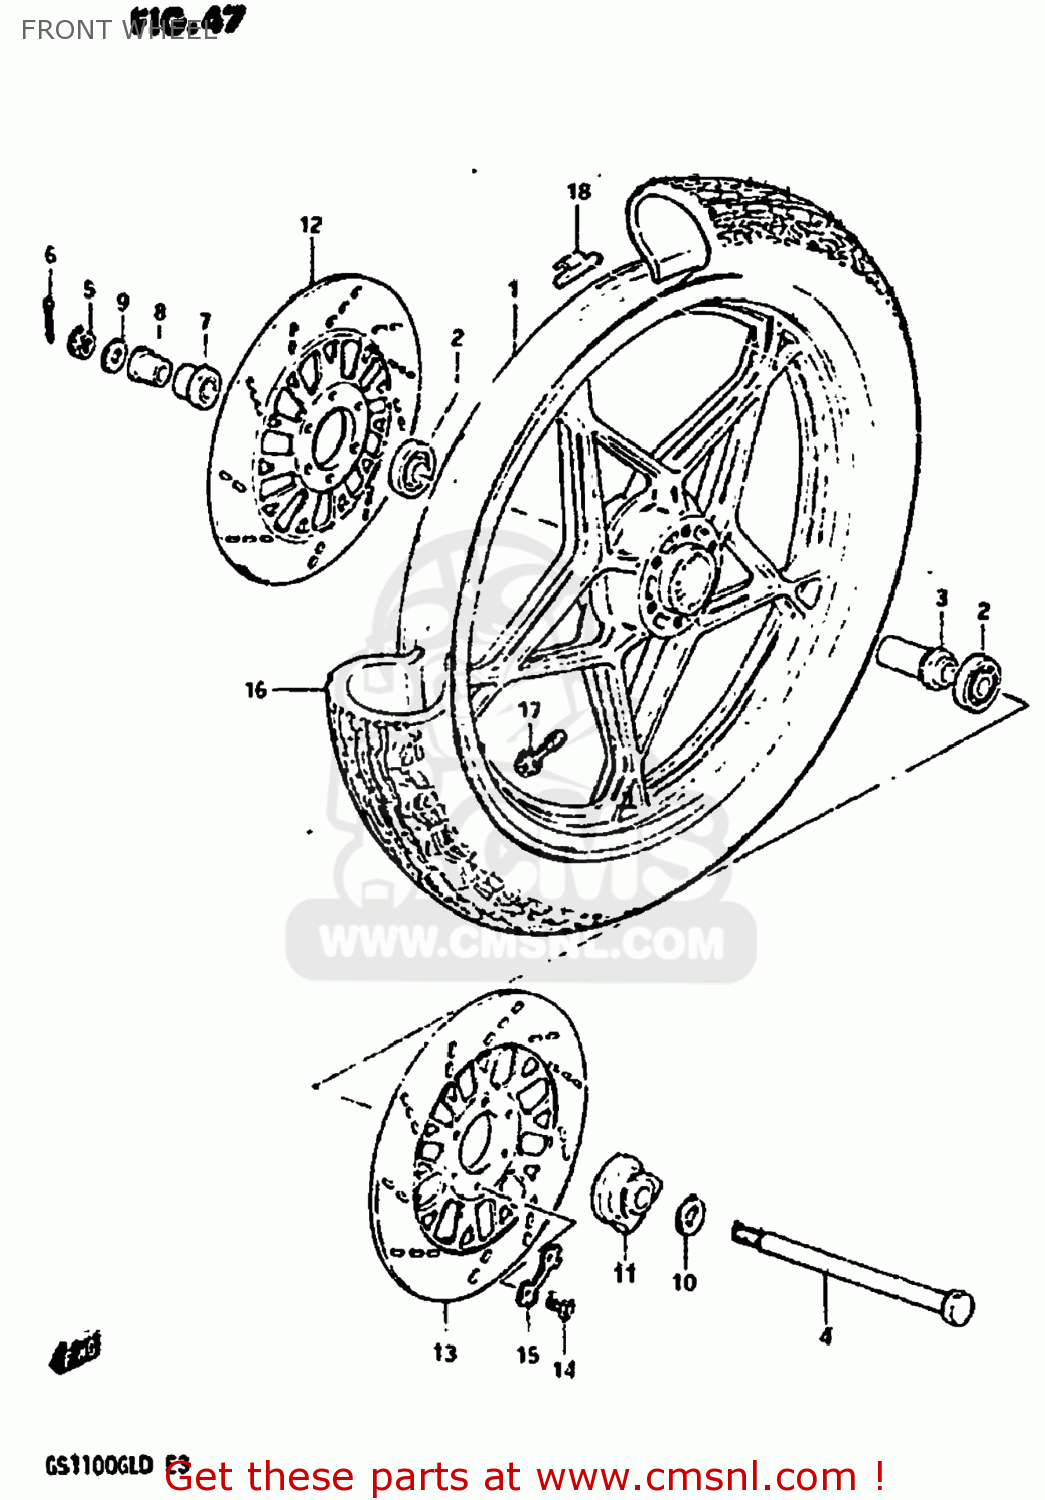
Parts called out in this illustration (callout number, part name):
1	CASTING WHEEL,FRONT 1.85
2	BEARING
3	SPACER,FR HUB BEARING
4	AXLE,FR
5	NUT 12MM
6	COTTER PIN
7	SPACER,FR AXLE,R
8	SPACER
9	WASHER
10	WASHER(15.5X26X2.3)
11	BOX ASSY,SPEEDOMETER GEAR
12	DISC,FR BRAKE,R
13	DISC,FR BRAKE,L
14	BOLT(8X25)
15	WASHER
16	TIRE,FRONT
17	VALVE ASSEMBLY,WHEEL RIM,J
18	BALANCER,WHEEL
